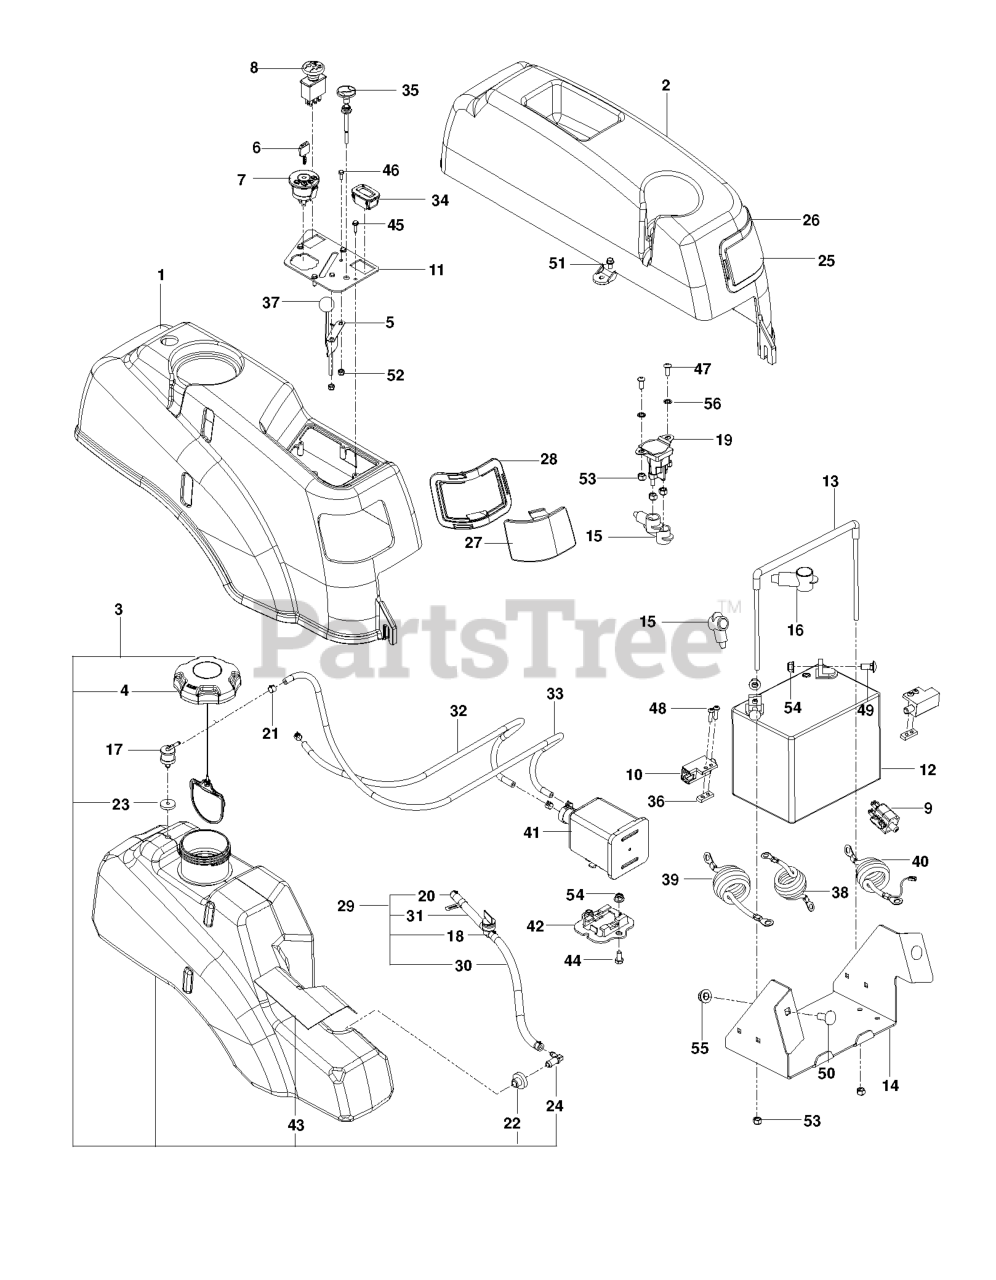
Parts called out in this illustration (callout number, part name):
1	FENDER RT, GRAY
2	FENDER, LT
3	TANK.FUEL.ASSEMBLY.LARGE
4	CAP, FUEL
5	THROTTLE CABLE
6	KEY MLD GEN DELTA
7	RP IGNITION SWITCH
8	RP SWITCH.PTO.8.TERMINAL.RED
9	SWITCH, BRAKE 3P
10	SWITCH INTERLOCKT
11	CONSOLE.PLATE.BLACK
12	BATTERY, 12 V 330 AMP
13	BATTERY TIE DOWN ASSEMBLY
14	BOX, BATTERY, BLACK
15	TERMINAL COVER-SM
17	VALVE.FUEL.CHECK
18	FUEL VALVE
20	HOSE CLAMP
21	CLAMP, HOSE
22	RUBBER GROMMET
23	GROMMET, CHECK VALVE
24	STEM, FUEL TANK
25	LENS, COLORED LEFT
26	LEFT HEADLIGHT RIM GREY
27	LENS, COLORED RIGHT
28	RT HEADLIGHT RIM GREY
29	FUEL LINE ASSY
30	GAS LINE 10"
31	FUEL LINE 3"
32	HOSE, VAPOR 3/16 X 30"
33	HOSE, VAPOR 3/16 X 39"
34	RP.GUAGE.SRVCMNDR.HRMTR.
35	CHOKE CABLE
36	TAPPED PLATE
37	KNOB.ROUND.BALL.BLACK
38	CABLE POSITIVE, LONG
39	BATTERY CABLE, NEGATIVE
40	CABLE POSITIVE LONG W/LEAD
41	CANNISTER, CARBON
42	BRACKET, CANISTER
43	SHIELD, HEAT
44	HCS 5/16-18 X 5/8 GR 5 ZD
45	SCR #10-12X3/4 HEX WAS HD ZD
46	HCS #10-24 X 1/2
47	SCR 1/4-20 X 5/8 BTN SKT HD ZD
48	SCR #10-24 X .75 SKT HD BLK
49	BOLT 5/16C X 3/4" CARRIAGE
50	RHSNB 3/8C X 1
51	BOLT 1/4-20 X 1/2 HWST
52	NUT 10-24 NYLOC
53	NUT.1/4-20.HEX.NYLOC.ZD
54	5/16-18 NYLOC FLANGE NUT
55	NUT 3/8-16 HEX FLG NYLOC ZD
56	WASHER 1/4 INT TOOTH
